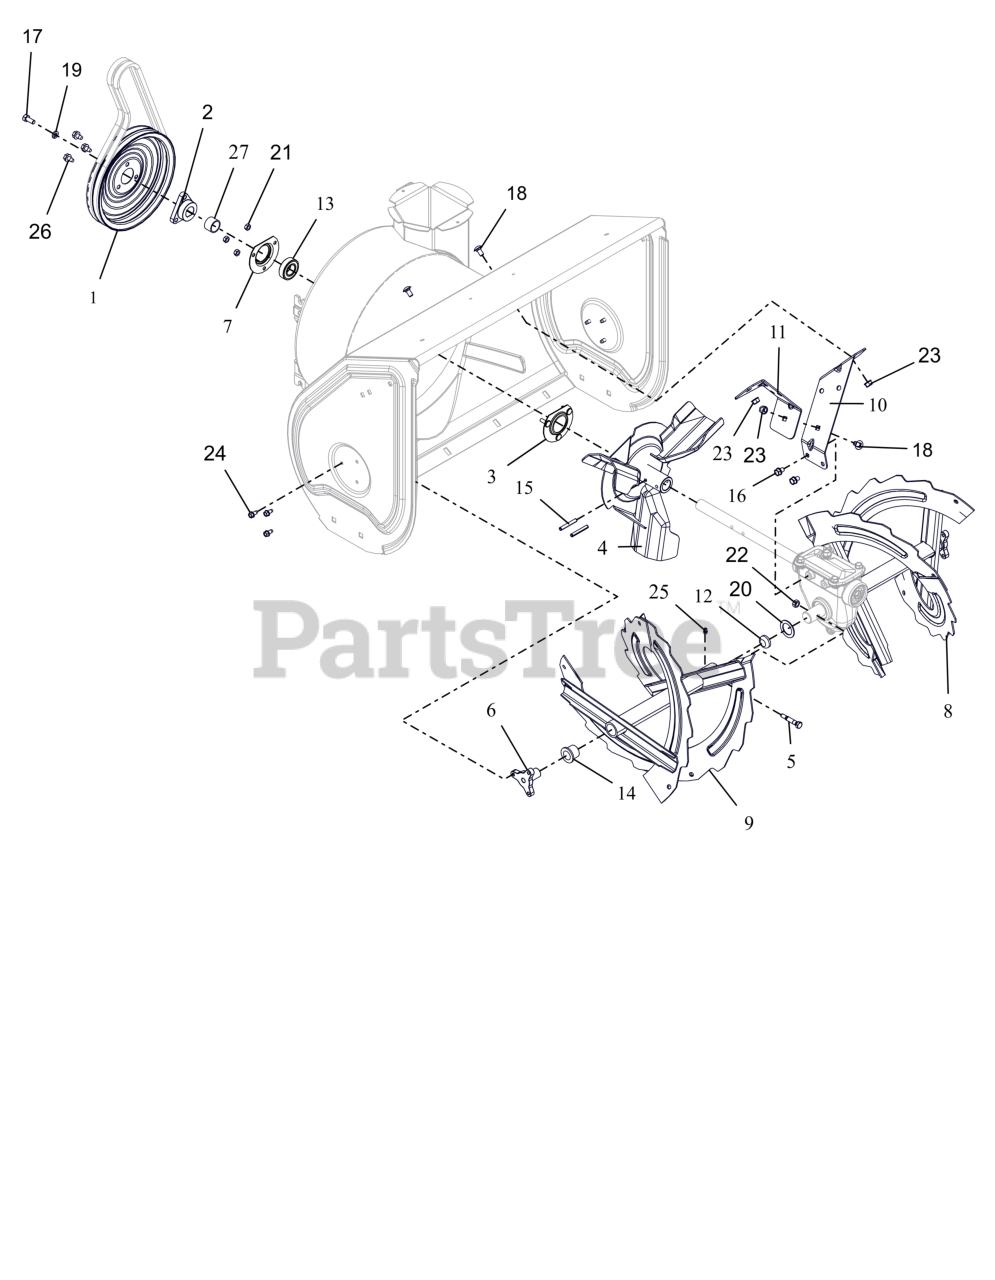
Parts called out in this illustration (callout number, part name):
1	PULLEY, SPIN FORM DUAL GROOVE
2	PULLEY HUB, D-BORE .87 PRO
3	BEARING FLANGE
4	IMPELLER, 3 BLADE-14"
5	SHEAR BOLT SERVICE ASSEMBLY
6	SUPPORT, RAKE BUSHING
7	BEARING FLANGE
8	RAKE, LH W/ZERK - 28"
9	RAKE, RH W/ZERK - 28"
10	BRACKET, GEARCASE SUPPORT - LH
11	BRACKET, GEARCASE SUPPORT - RH
12	PLUG, RAKE TUBE
13	BRG-BALL .876X1.75X.50 RSTFP
14	BSHG-FLG, NY.778 ID X 1.018 OD
15	PIN-ROLL .250X1.75
16	BLT, SEMS .31-18X.50 G5 ZCC
17	BLT, HEX .31-24X.750 G5 ZCC
18	BLT,RHSSN.31-18X.625 G5 ZCCP30
19	WSHR, LK-HVY .312X.097 ZCC
20	WSHR, FLT 1.010X1.505X.062 ZCC
21	NUT,LK-CTR .25-20 GA ZCC
22	NUT,LK-CTR .31-18 GA ZCC
23	NUT-LK-TOP-FLG .312-18 GF ZCC
24	SCR-TAP .25-20X.50 HWH ZCC
25	ZERK,FITTING .25X.125 DRIVE IN
26	SCR,TAP .312-18X.50 HWH TR ZCC
27	BSHG,SPCR .895X1.065X.693
